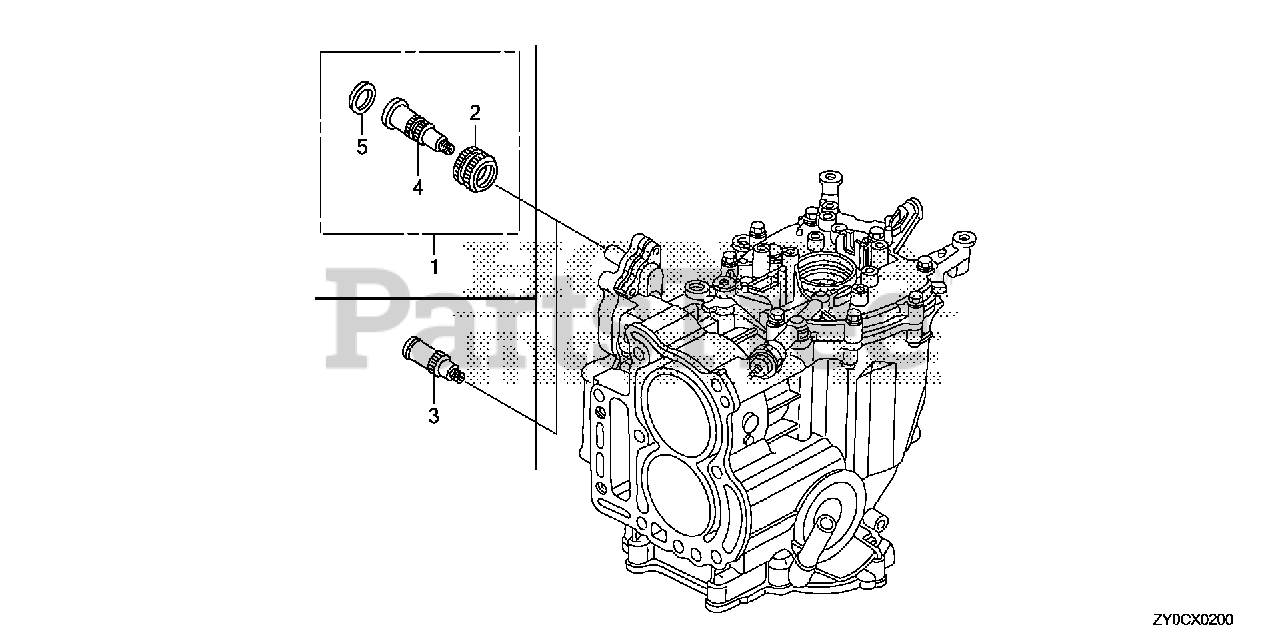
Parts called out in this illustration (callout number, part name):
1	JOINT KIT, WATER HOSE
2	NUT, WATER MOUTH
3	JOINT, WATER HOSE
4	JOINT, WATER HOSE
5	SEAT, WATER MOUTH
